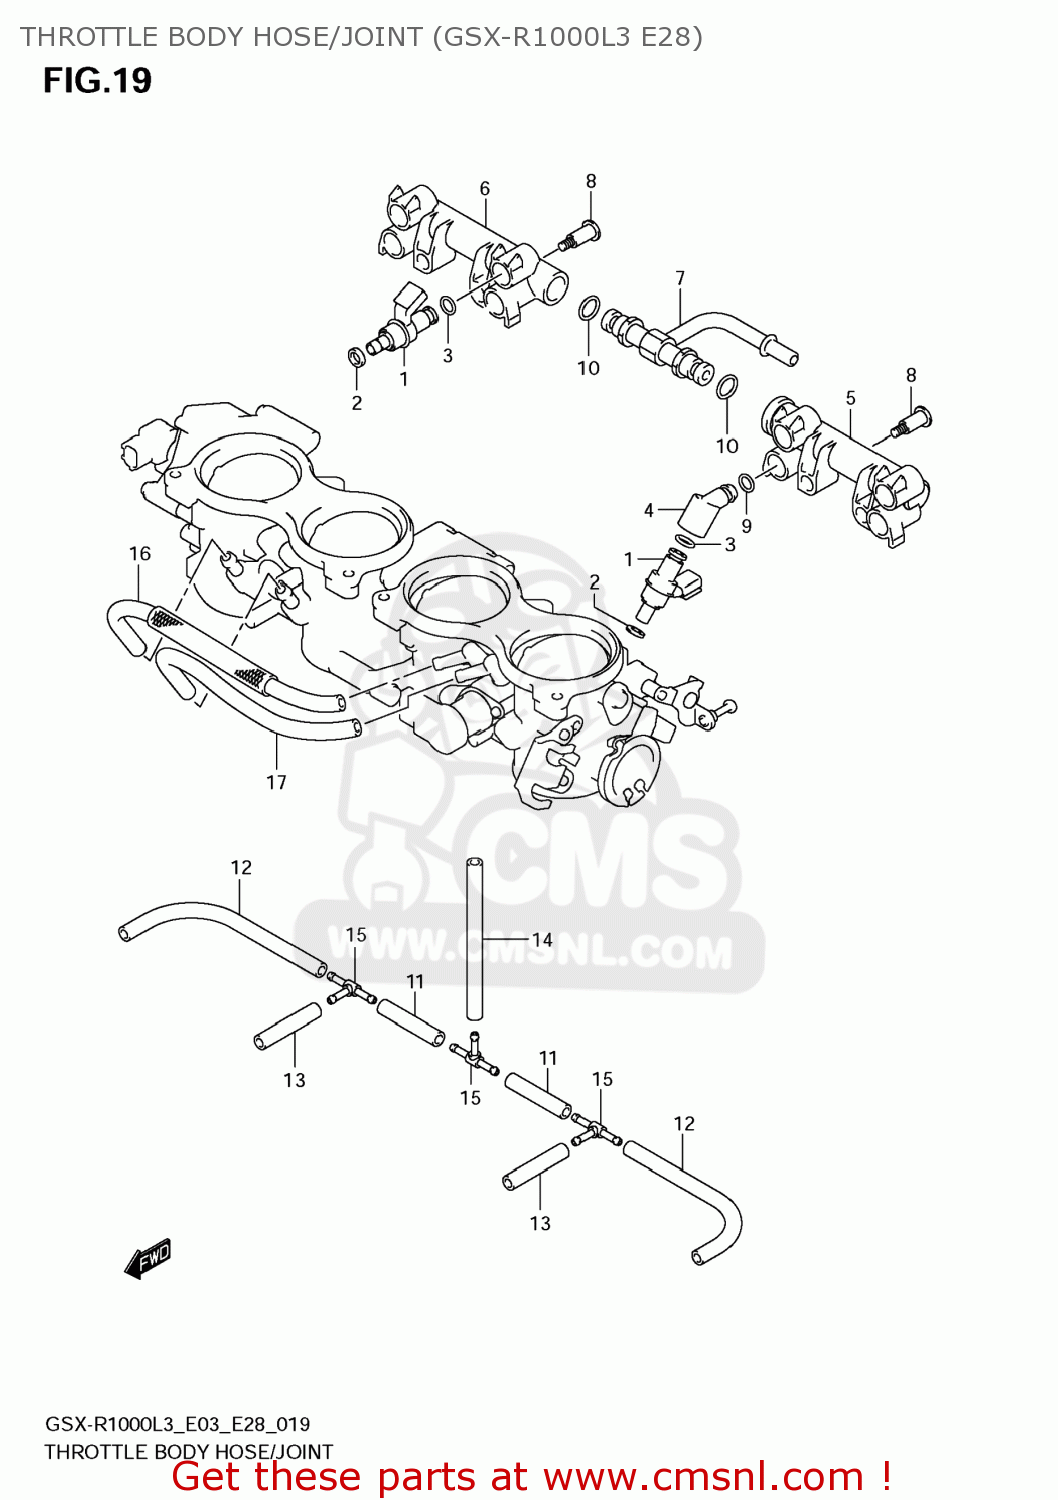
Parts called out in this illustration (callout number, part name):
1	INJECTOR ASSY
2	RING,SEAL
3	O RING
4	PIPE,FUEL
5	PIPE,FUEL
6	PIPE,FUEL
7	JOINT
8	SCREW
9	O RING
10	O RING
11	HOSE
12	HOSE
13	HOSE
14	HOSE
15	JOINT
16	TUBE
17	TUBE
